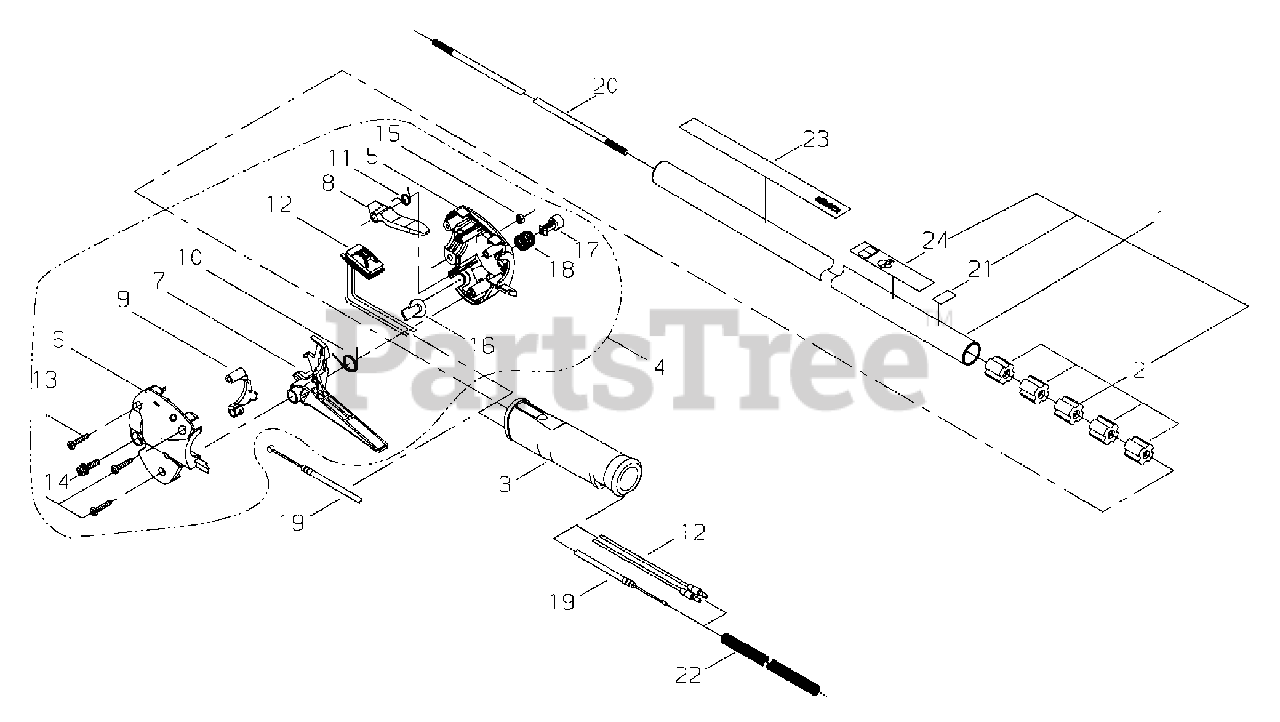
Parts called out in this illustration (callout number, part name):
1	MAIN PIPE ASSY
2	BUSHING
3	GRIP
4	THROTTLE LEVER ASSY
5	HANDLE, CONTROL - RIGHT
6	HANDLE, CONTROL - LEFT
7	TRIGGER, THROTTLE
8	LEVER, TRIGGER LOCKOUT
9	LOCKOUT, THROTTLE
10	SPRING
11	SPRING
12	SWITCH, IGNITION
13	SCREW - 4X20 -- TAPPING
14	SCREW - 5X20
15	NUT - 5
16	PLUG
17	BUTTON, THROTTLE LOCK
18	SPRING
19	CABLE, THROTTLE
20	PIPE, MAIN
21	LABEL - INSTRUCTION
22	TUBE
23	LABEL - TRADE
24	LABEL - CAUTION
